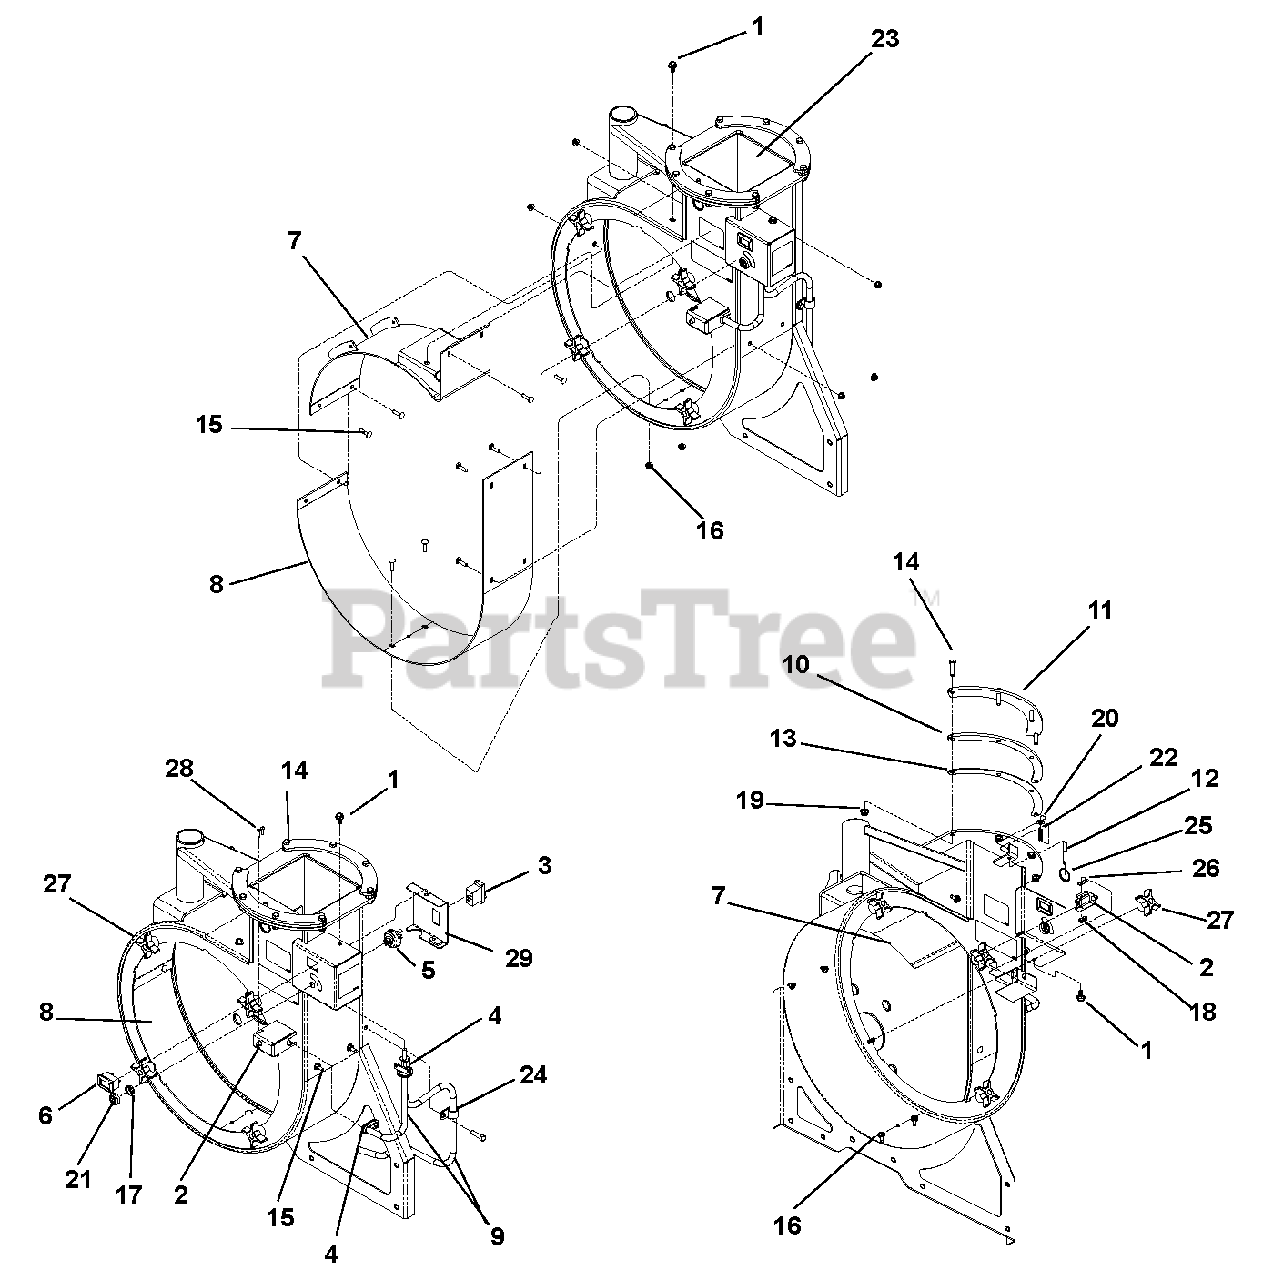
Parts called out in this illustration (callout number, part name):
1	Bolt, 5/16-18 x .625 Grade 5
2	Switch, Plunger N.O.-N.C
3	Switch, Rocker Momentary Rev 0
4	Grommet, Rubber .881 D x .14 GR
5	Key Switch
6	Meter, Hour Smart Sense without SV
7	Baffle, 22 HP (995841)
8	Plate, Liner 22 HP (995841)
9	Wire Harness, Truck Loaders
10	Spacer, Flange
11	Flange, Top
12	Pin, Spring Latch
13	Spacer, Flange .060
14	Bolt, Hex .31-18 x 1.25 Grade 5 YWZC
15	Bolt, Round Head Square Neck .25-20 x 1.00 Grade 5 YWZC
16	Nut, .25-20 Nyloc Flange
17	Nut, Panel .562-24 Grieco
18	Nut, Nyloc 10-24 w/insert YWZX
19	Nut, Nyloc .31-18 Flange YXZC
20	Washer, Flat .281 x .62 x .065 Stl YWZC
21	Cap, Ignition Switch
22	Spring, Compression .028 x .34 x 1.062
23	Weldment, Fan Housing Assembly w/Decals 22 HP (995841)
24	P-Clip, Insulated .750
25	Ring, Retaining
26	Strip, Backup
27	Knob, 5/16 Thread
28	Screw, Machine 8-32 x .62 Nickel
29	Weldment, Switch Cover
